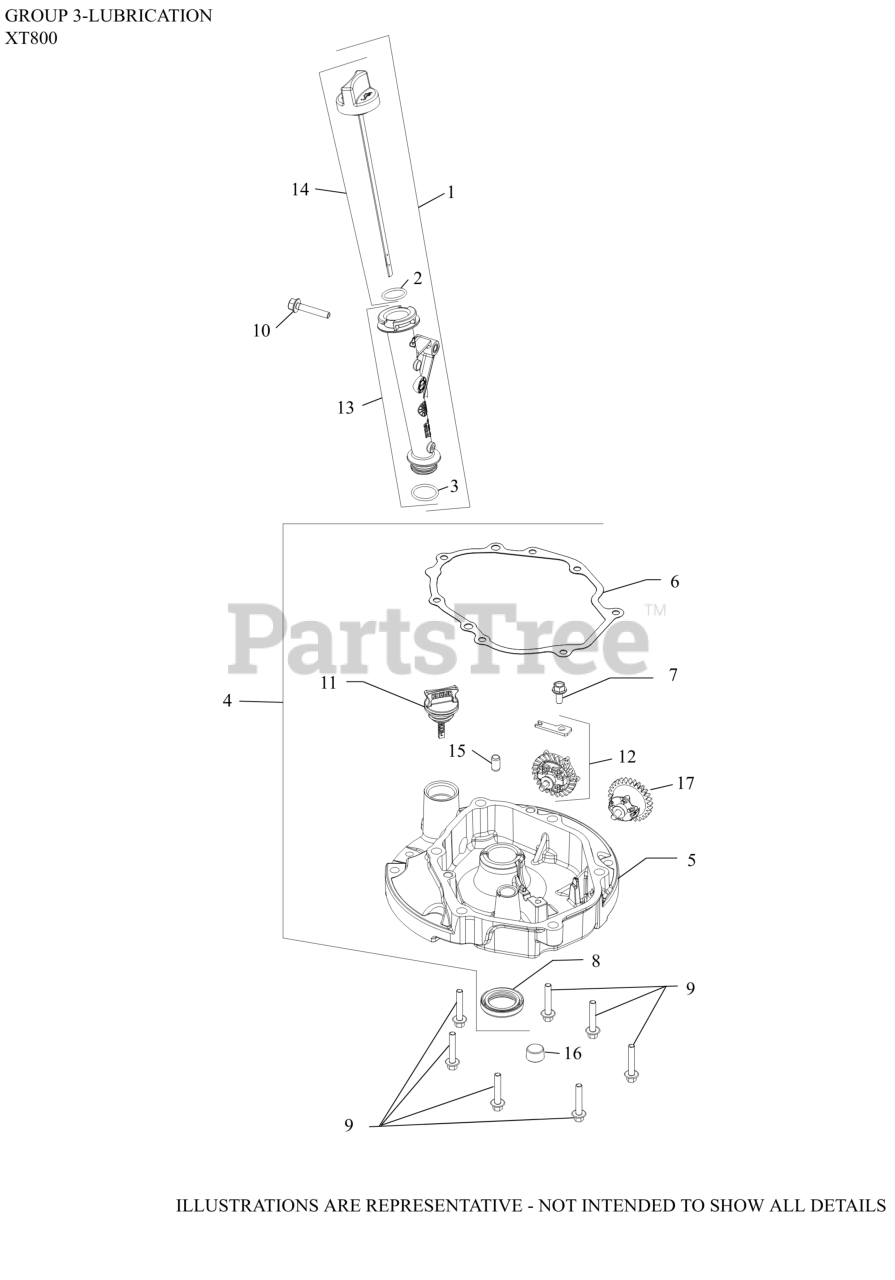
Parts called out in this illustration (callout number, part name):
1	KIT, DIPSTICK AND TUBE-(#1412320S)
2	O-RING (CAP)
3	O-RING, OIL FILL TUBE
4	KIT, OIL PAN
6	GASKET, OIL PAN
9	SCREW, HEX FLANGE (M8)-USE 25 086 456-S
10	SCREW, HEX FLANGE (M6)-(#25086435S)
12	GEAR ASSEMBLY, GOVERNOR
13	TUBE ASSEMBLY, OIL FILL
14	CAP, DIPSTICK ASSEMBLY
15	PIN, DOWEL (8MM)
16	PLUG, PIPE (W/SEALANT)
NI	GOVERNOR ASSEMBLY-USE 17 310 08-S
